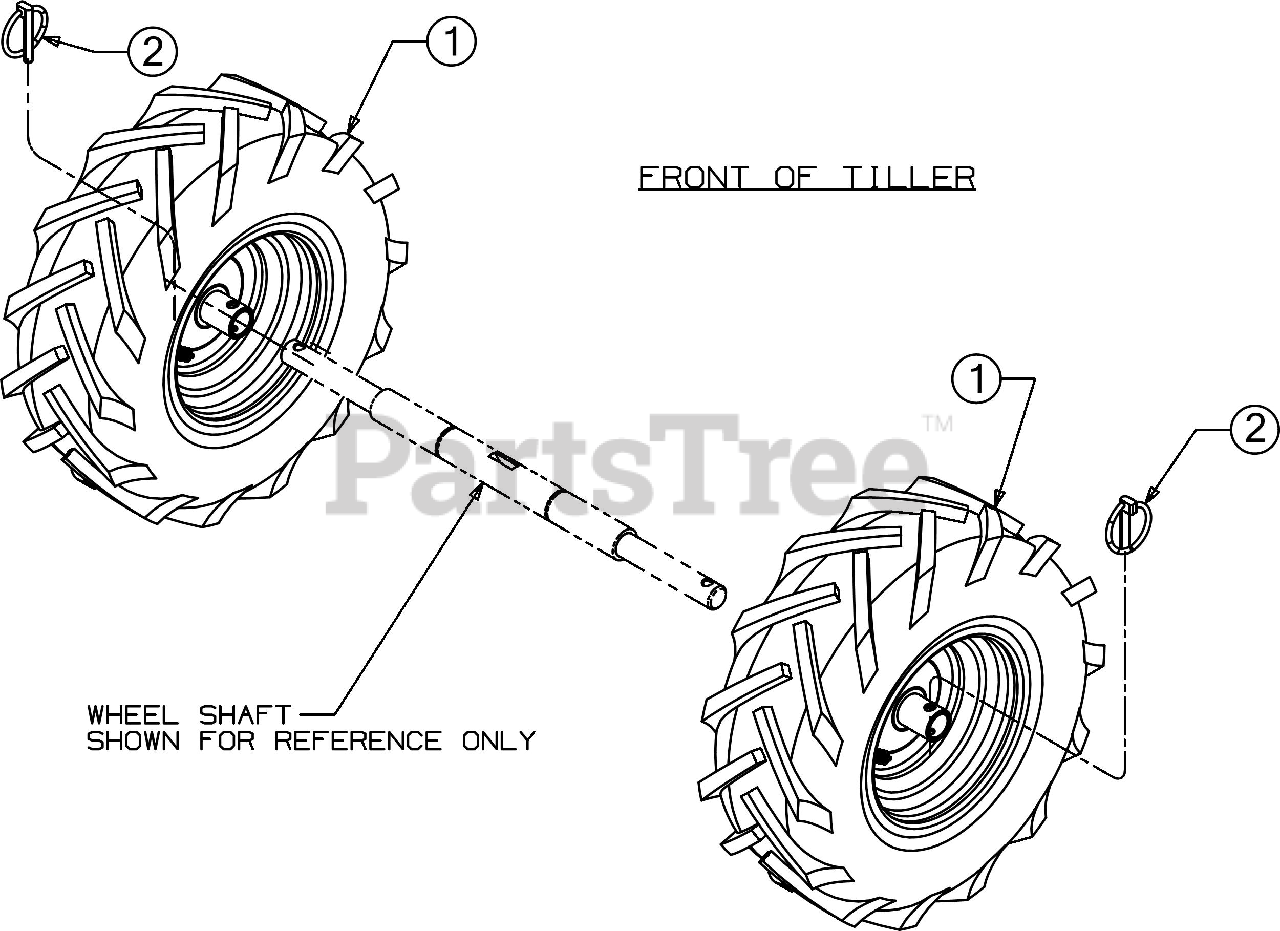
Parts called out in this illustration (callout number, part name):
1	WHEEL ASSEMBLY (13 X 5-6) (BEIGE)
1	RIM ASSEMBLY (6 X 3.25) (BEIGE)
1	TUBELESS VALVE
1	TIRE 13 X 5.0 X 6.00
